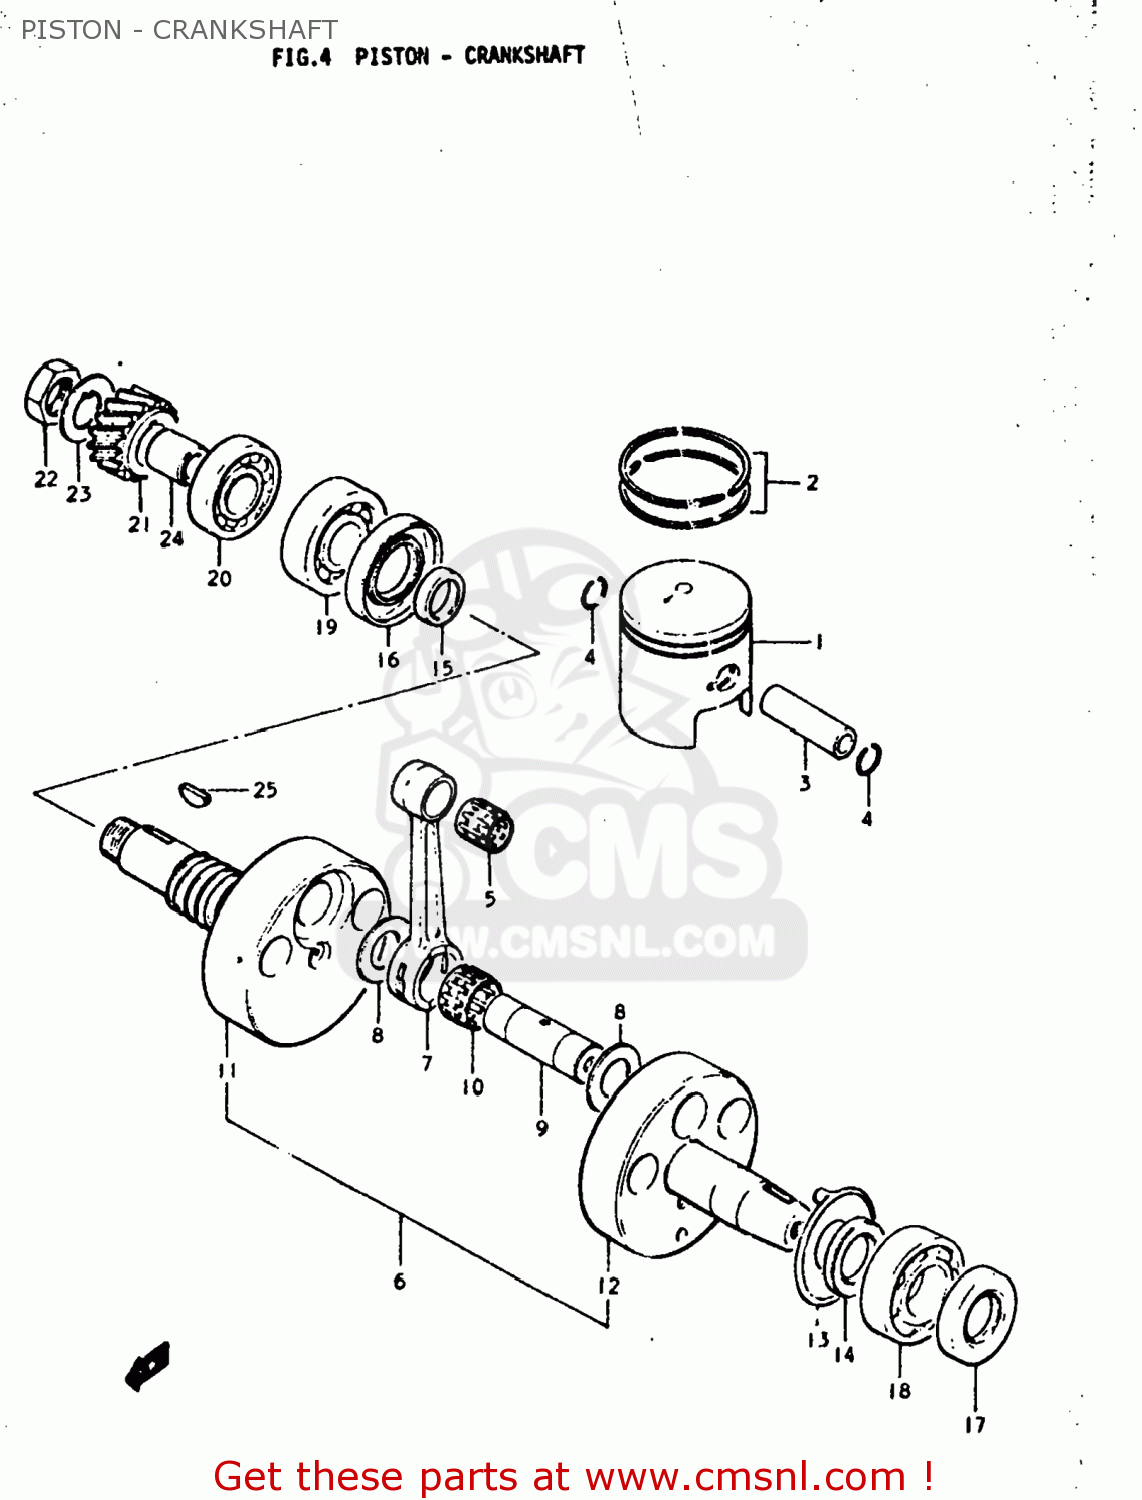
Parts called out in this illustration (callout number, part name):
1	PISTON
2	RING SET,PISTON
3	PIN,PISTON
4	RING,SNAP 16MM
5	BEARING
6	CRANKSHAFT ASSEMBLY
7	CONNECTING ROD
8	WASHER
9	PIN,CRANK
10	ROLLER BEARING (24X30X1
11	CRANKSHAFT
12	CRANKSHAFT,LEFT
13	PLATE,CSHAFT OIL GUIDE
14	SPACER
15	SPACER
16	OIL SEAL
17	OIL SEAL
18	BEARING(25X62X17)
19	BEARING
20	BEARING
21	GEAR,PRIMARY DRIVE
22	NUT
23	WASHER
24	SPACER
25	KEY
